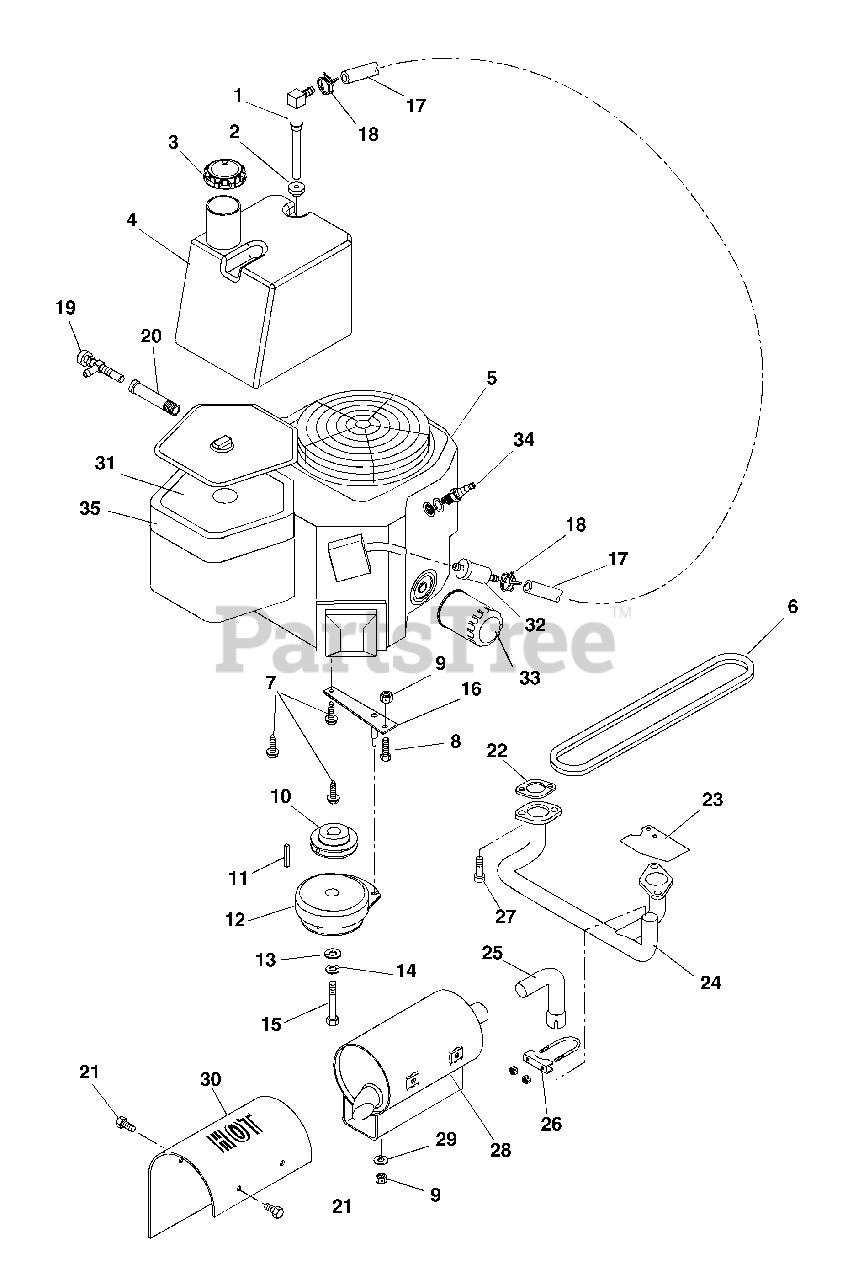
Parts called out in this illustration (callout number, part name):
1	Fitting, Tank
2	Bushing
3	Cap, Gas
4	Tank, Fuel
5	Engine, 27HP Kohler 6-Pin (018)
5	Engine, 25HP Kawasaki (020)
6	V-Belt A-Section 24.90 x .500 /.031
7	Screw-Tapping Hex-Washer-Head .38-16 x 1.00
8	Bolt-Hex .31-18 x 1.75 Grade 5
9	Nut-Locking-Center .31-18
10	Pulley-4.46 Dia. x 1.12 Bore
11	Key-Square .25 x 1.00 x .25
12	Electric Clutch
13	Washer-Flat-Steel .515 x 1.625 x .250
14	Washer-Locking .44 x .109
15	Bolt-Hex .44-20 x 3.00 Grade 5
16	Anchor-Clutch
17	Gas Line-Bulk 1/4" ID
18	Hose-Clamp
19	Nipple, Pipe .38 x 6.00 Unfinished Steel
20	Pipe Cap
21	Bolt, Hex M5 - .8 x 8 mm
22	Gasket-Exhaust (018)
23	Heat Deflector (018)
24	Manifold-Kohler CV18-27 (018)
24	Manifold-Kawasaki, PM310 (020)
25	Tube, Manifold
26	U-Bolt, 1/4-20 x 1.50
27	Screw-Socket Head M8-1.25 x 20 mm
28	Muffler (Includes 09066300 Heat Shield)
29	Washer, Flat-Steel
30	Heat Shield (Included with 09065600 Muffler)
31	Air Filter (018)
31	Air Filter (020)
32	Fuel Filter
33	Filter, Oil- Kohler CV20 (018)
33	Filter, Oil- Kawasaki (020)
34	Spark Plug (018)
34	Spark Plug (020)
35	Element, Precleaner (018)
35	Element, Precleaner (020)
